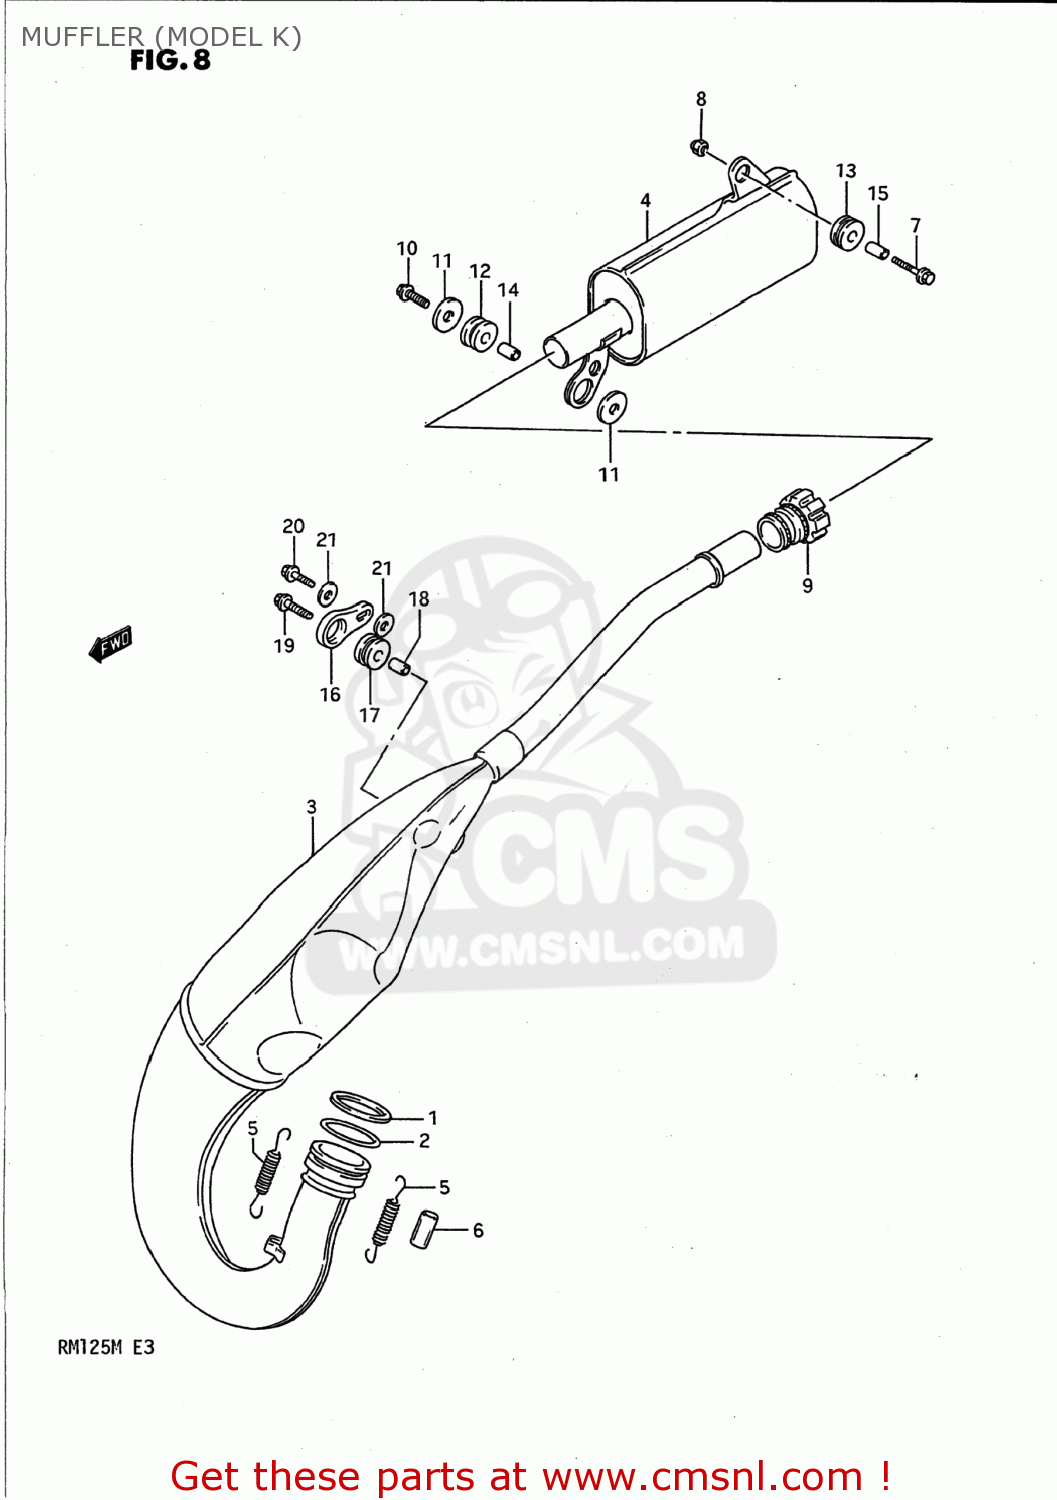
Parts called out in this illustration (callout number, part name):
1	WASHER,EXHAUST PIPE
2	O RING,EXHAUST PIPE
3	BODY,MUFFLER,FIRST
4	BODY,MUFFLER
5	SPRING
6	HOSE
7	BOLT
8	NUT 6MM
9	CONNECTOR,2ND MUFFLER
10	BOLT
11	WASHER (6.5X29X1.6)
12	CUSHION
13	CUSHION
14	SPACER (6.8X10X9)
15	SPACER(6.5X11.5X13)
16	PLATE,MUFFLER MTG
17	CUSHION,MUFFLER
18	SPACER(6.4X9X16)
19	BOLT
20	BOLT
21	WASHER (6.5X20X1.2)
